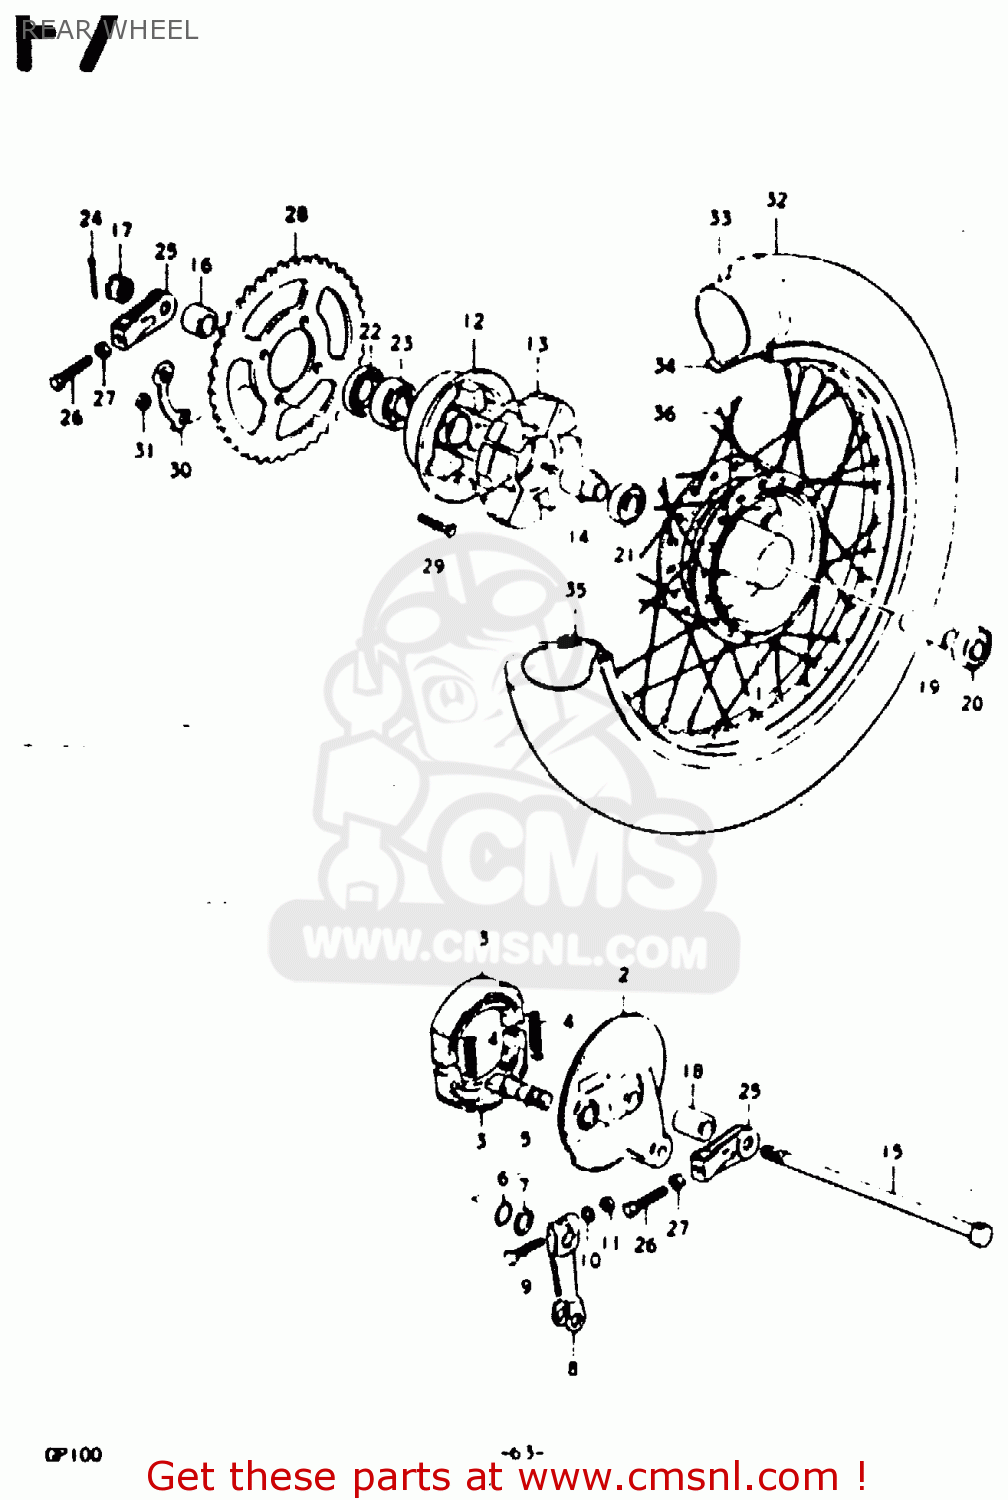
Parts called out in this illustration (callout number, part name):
1	HUB, WHEEL
2	PANEL
3	SHOE,BRAKE
4	SPRING(L:34)
5	CAM,FRONT BRAKE
6	O-RING (D:2.4 ID:13.8)
7	WASHER (14.5X22X1.6)
8	LEVER,RR BRAKE CAM
9	BOLT(6X33)
10	WASHER
11	NUT
12	DRUM,RR SPROCKET MOUNTING
13	CUSHION,REAR DRUM
14	RETAINER,RR SPROCKET DRUM
15	AXLE, REAR
16	SPACER 12X25X2
17	NUT 12MM
18	SPACER(12.2X22X39)
19	SPACER (12.6X19X58)
20	BEARING
21	BEARING
22	SEAL OIL(25X40X6)
23	BEARING
24	COTTER PIN
25	ADJUSTER, CHAIN
26	BOLT
27	NUT
28	SPROCKET,RR
29	BOLT(8X33.5)
30	WASHER
31	NUT
32	TIRE (2.75-18)
33	TUBE,INNER
34	PROTECTOR,WHEEL,INNER
35	RIM,WHEEL(1.40X18)
36	SPOKE SET,REAR
